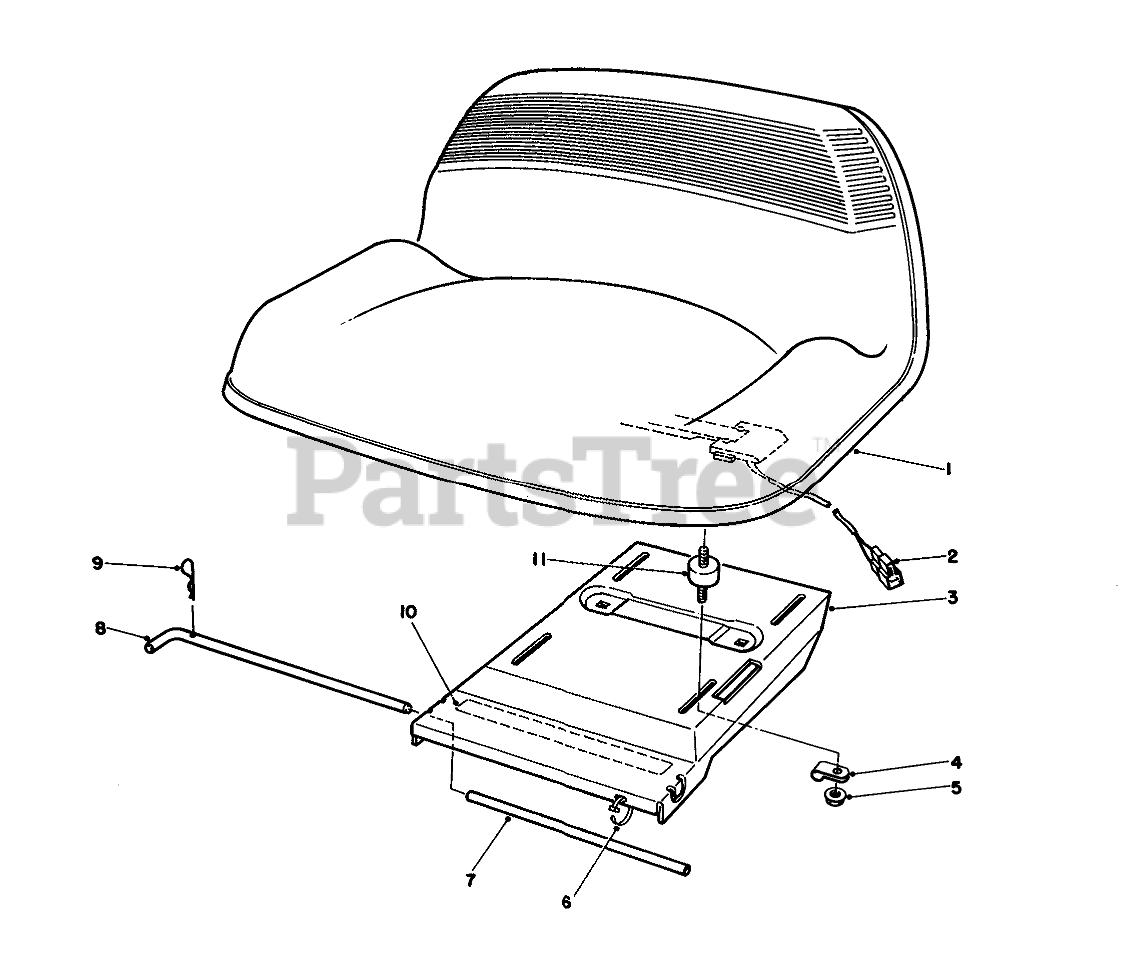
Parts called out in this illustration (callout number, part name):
2	SWITCH-SEAT
3	Base-Seat
4	CLAMP
5	NUT-HF
6	TIE-CABLE
7	TUBE-SEAT
8	ROD-SEAT BASE
9	PIN-COTTER
10	DECAL
11	ISOLATER-SEAT
